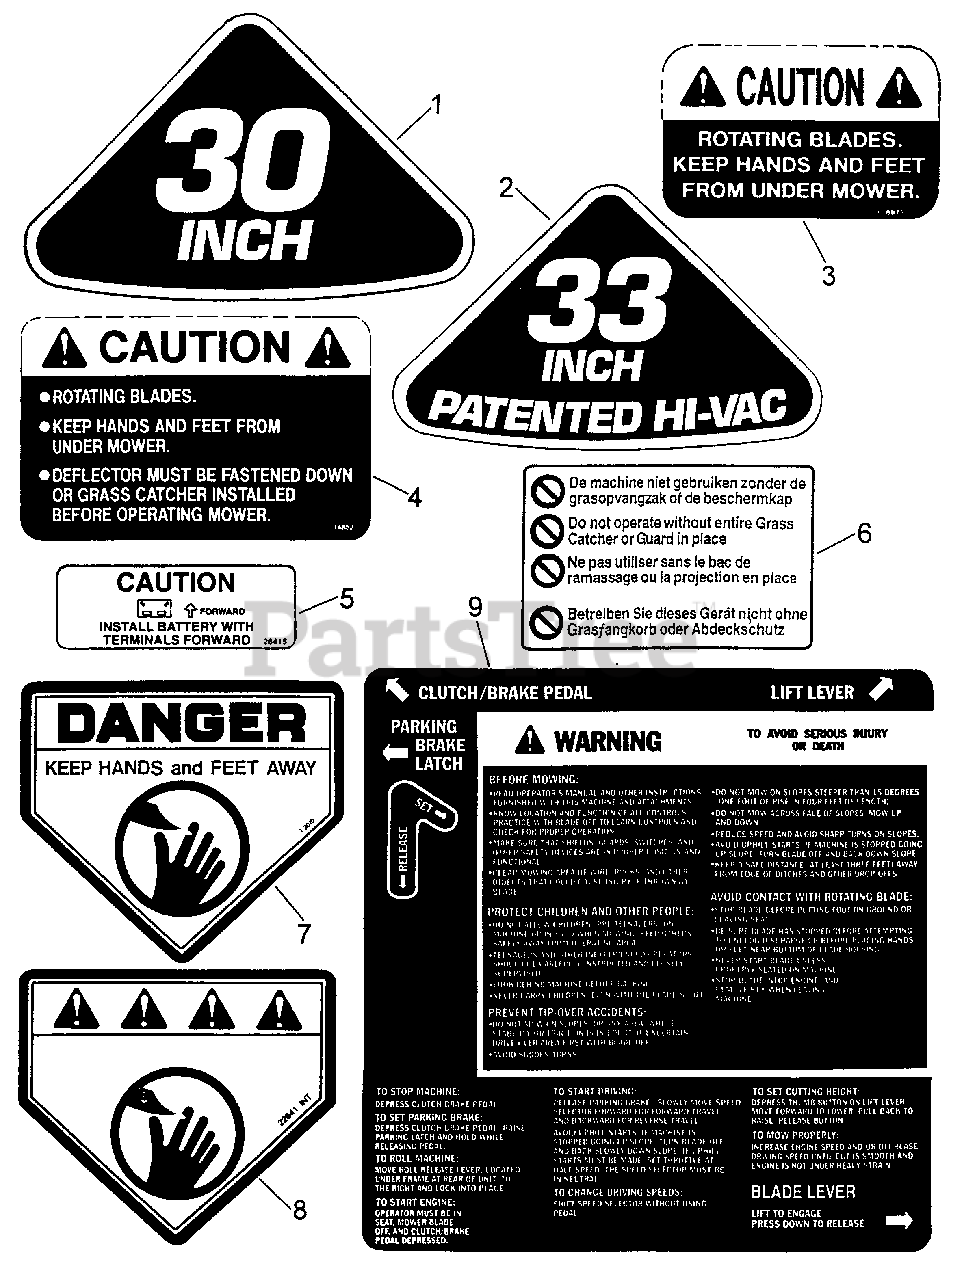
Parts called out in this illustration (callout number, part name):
1	DECAL, 30 Inch
2	DECAL, 33 Inch Hi-Vac
3	DECAL, Caution, Rotating Blades
4	DECAL, Caution, Rotating Blades
5	DECAL, Caution, Battery Location
6	DECAL, Deck/Chute international Warning
7	DECAL, Danger, Cut-Finger
8	DECAL, Cut-Finger (International)
9	DECAL, Instructions, Frame, Top (Hydro Drive Models)
9	DECAL (French Version of #9)
9	DECAL (German Version of #9)
9	DECAL (Dutch Version of #9)
10	DECAL (French Version of #10)
10	DECAL (German Version of #10)
10	DECAL (Dutch Version of #10)
